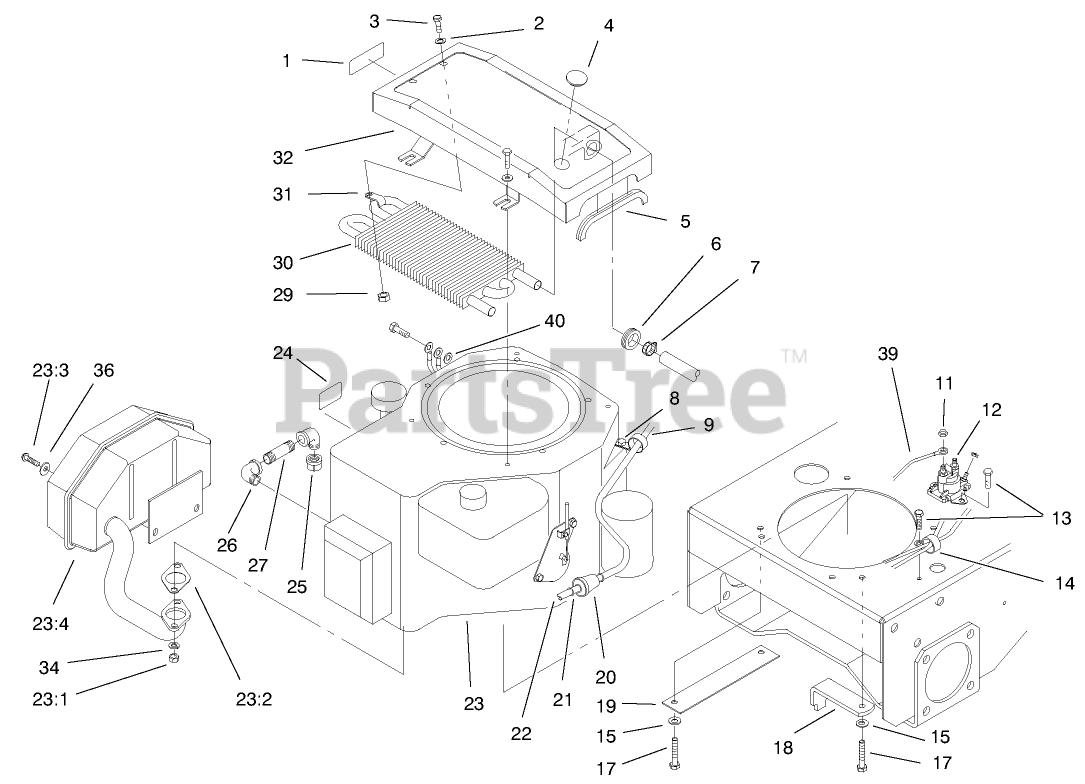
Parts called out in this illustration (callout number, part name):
1	DECAL-SHUT OFF, FUEL
2	WASHER-FLAT
3	SCREW-HH
4	PLUG-PLASTIC
5	TRIM-MOUNT, COOLER
6	GROMMET
7	CLAMP-HOSE
8	SCREW-SHWH
9	CLAMP-R
11	NUT-KEPS
12	Solenoid
13	SCREW-HWH
14	CLAMP-R
15	WASHER-PLAIN
17	SCREW-HH
18	RETAINER-CLUTCH
19	GUARD-PULLEY
20	FILTER-FUEL
21	CLAMP-HOSE
22	HOSE-FUEL
23	Engine-15 Hp Kohler
23:1	NUT-MUFFLER
23:2	GASKET-EXHAUST
23:3	SCREW-MUFFLER
23:4	MUFFLER
24	DECAL-SURFACE, HOT
25	CAP-PIPE
26	ELBOW-STREET, 90 DEG
27	NIPPLE
29	NUT-LOCK, NI
30	Cooler-Oil
31	CLAMP-R
32	MOUNT-COOLER
34	WASHER-LOCK
36	WASHER-FLAT
39	WIRE-SOLENOID/STARTER
40	NUT-MUFFLER
